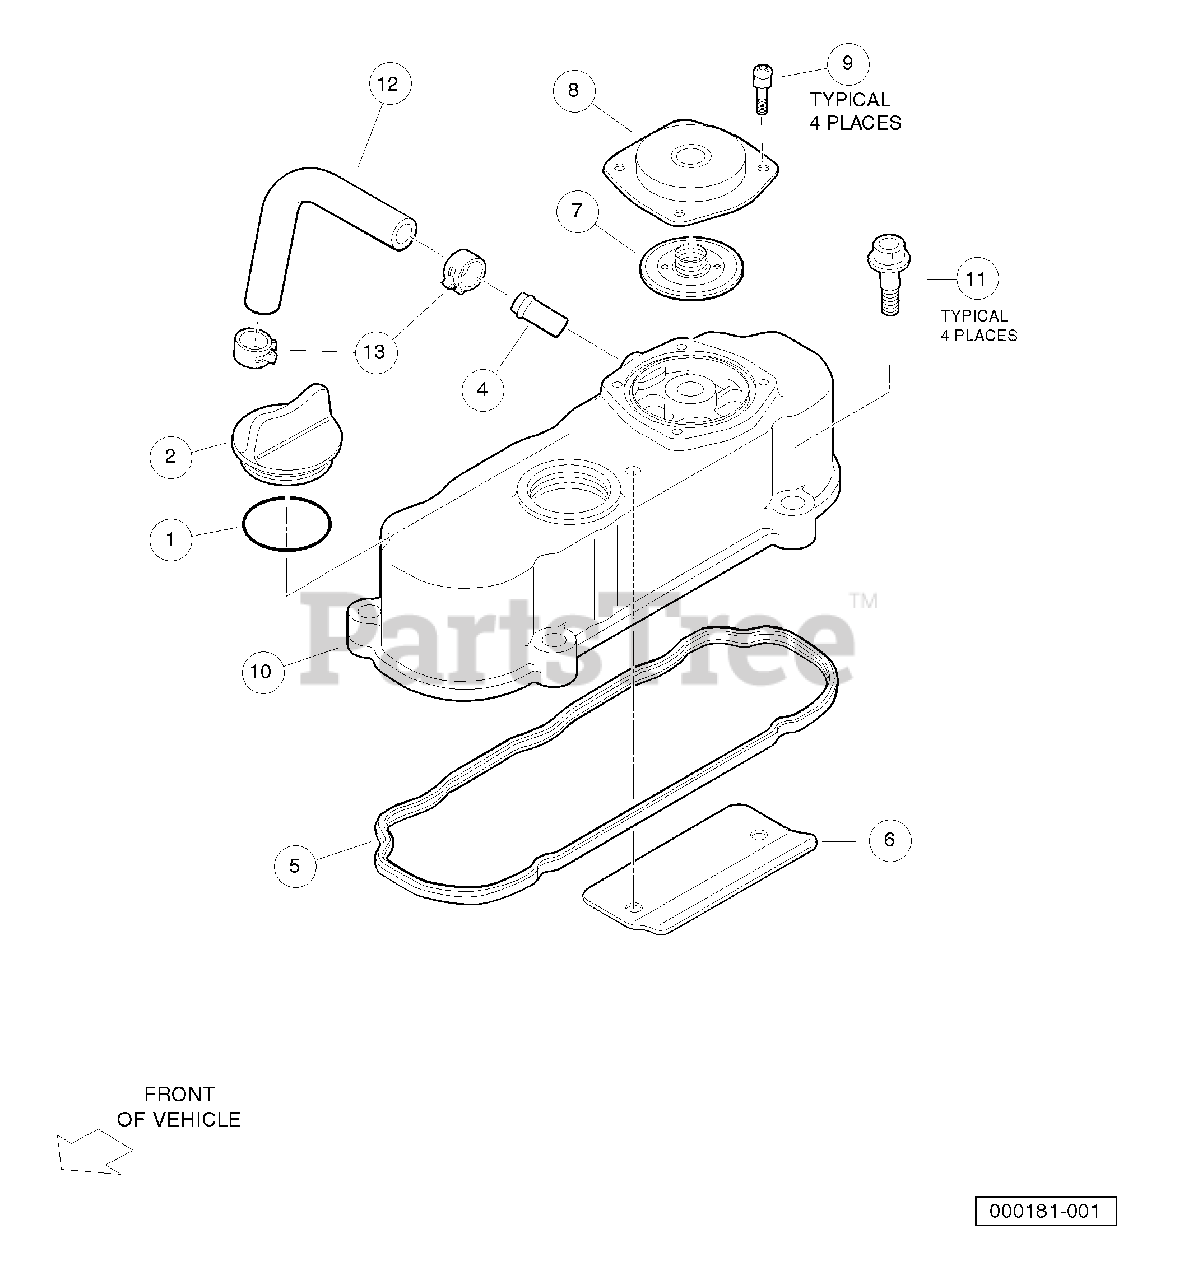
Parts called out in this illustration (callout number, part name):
1	O Ring, 30 X 36
2	Plug, Oil Filler
3	Assembly, Cylinder Head Cover
4	Pipe, Water Return, D722
5	Gasket, Cylinder Head Cover
6	Shield, Breather
7	Valve, Breather
8	Cover, Breather
9	Screw, Breather
10	Cover, Cylinder Head
11	Bolt, Cylinder Head Cover
12	Tube, Breather
13	Clamp, Breather Tube
